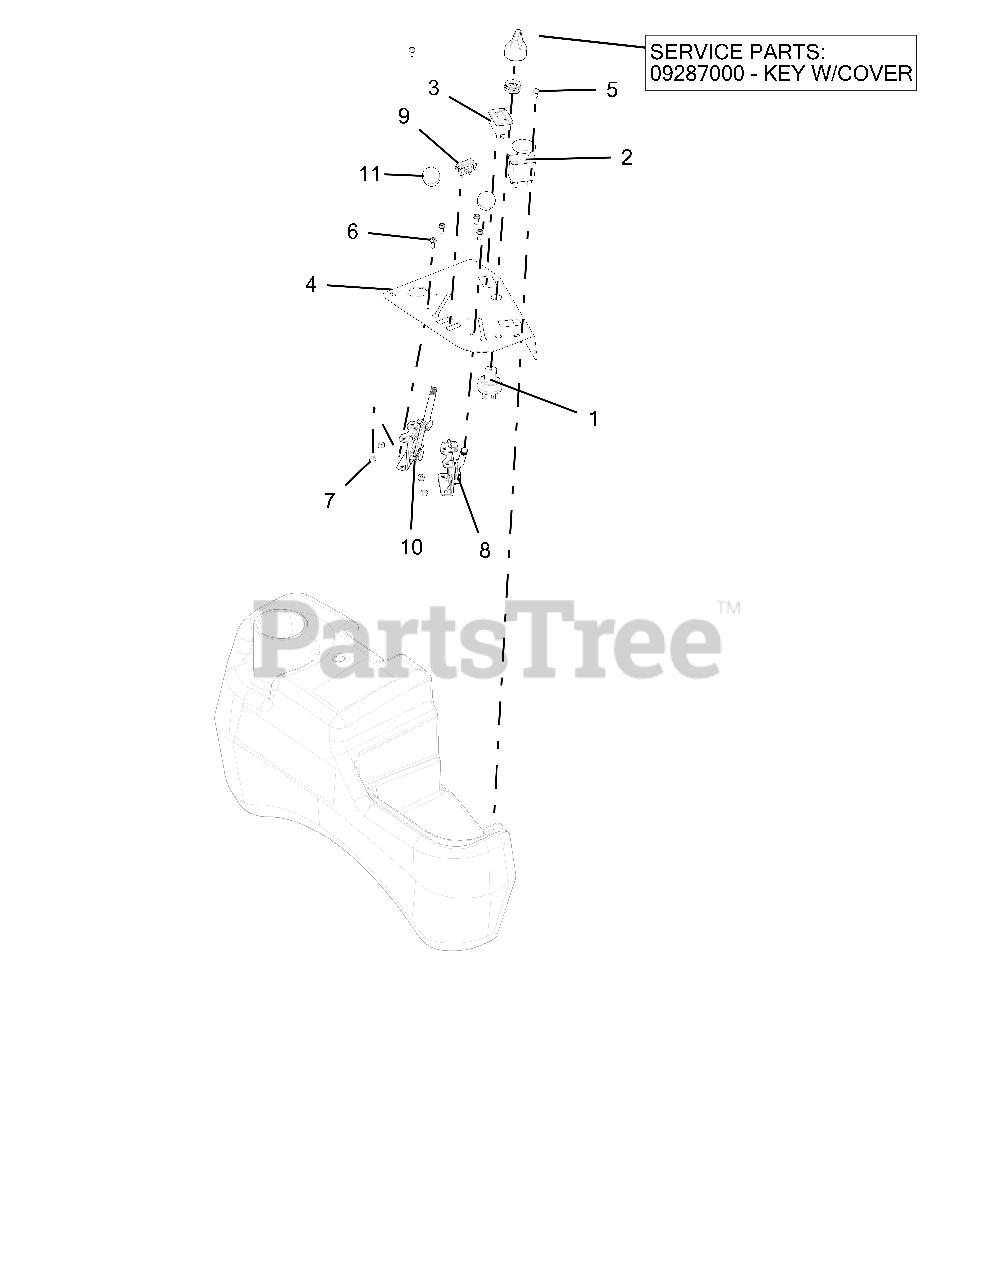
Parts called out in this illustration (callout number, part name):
1	SWITCH, IGNITION
2	SWITCH, CLUTCH
3	METER, HOUR W/MAINTENANCE
4	PANEL, CONTROL - PROTURN 100
5	SCR-MCH 10-24X.38 HWHSTAINLESS
6	@SCR-MCH 10-24X.50 HWH YWZC
7	NUT-LK-NYL #10-24 YWZC
8	CABLE, THROTTLE 53"
9	LIGHT, INDICATOR
10	CABLE, PRO-CONTROL THROTTLE
11	KNOB, CONTROL BLACK .38-16X.50
12	KEY W/COVER
